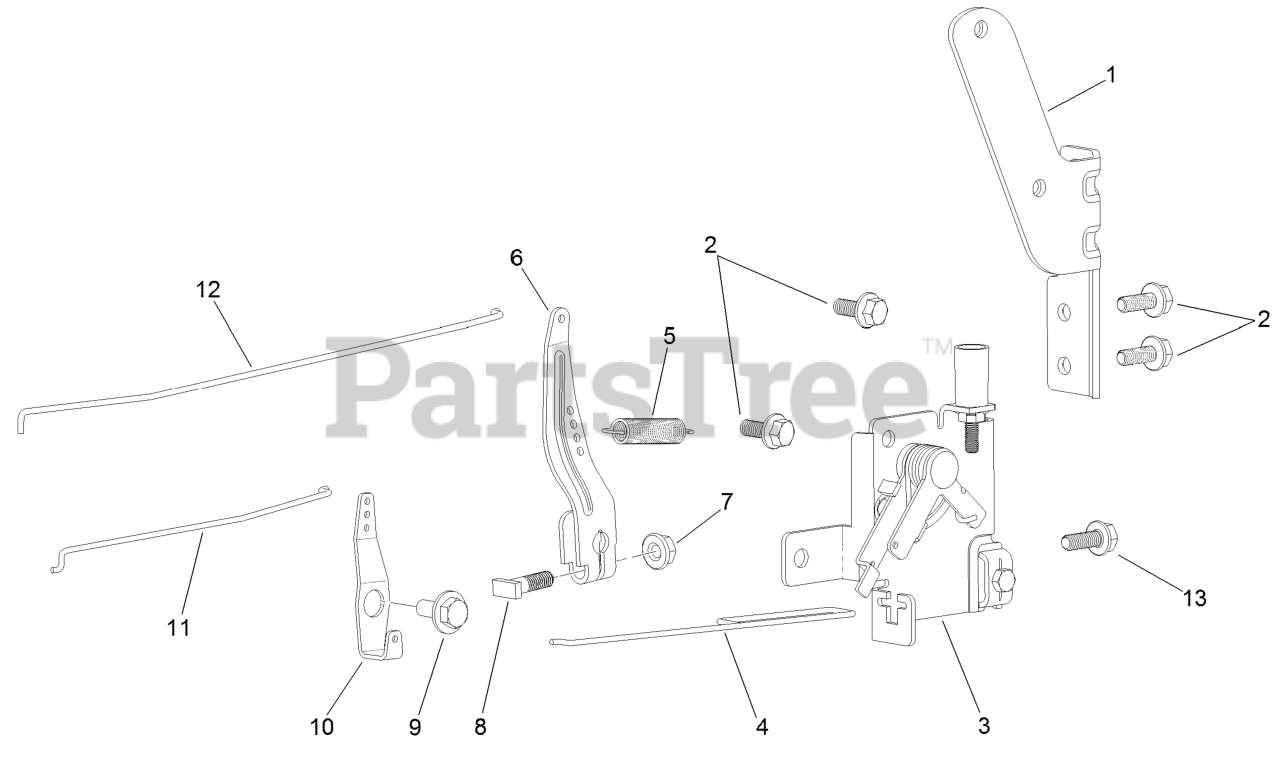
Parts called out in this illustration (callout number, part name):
1	BRACKET-PUMP, FUEL
2	SCREW-HHF
3	CONTROL-THROTTLE
4	ROD-THROTTLE
5	SPRING-GOVERNOR
6	ARM-GOVERNOR
7	NUT-FLANGE
8	BOLT-ARM, GOVERNOR
9	SCREW-SHOULDER, HHF
10	BELLCRANK-CHOKE
11	ROD-CHOKE
12	ROD-GOVERNOR
13	SCREW-HHF
